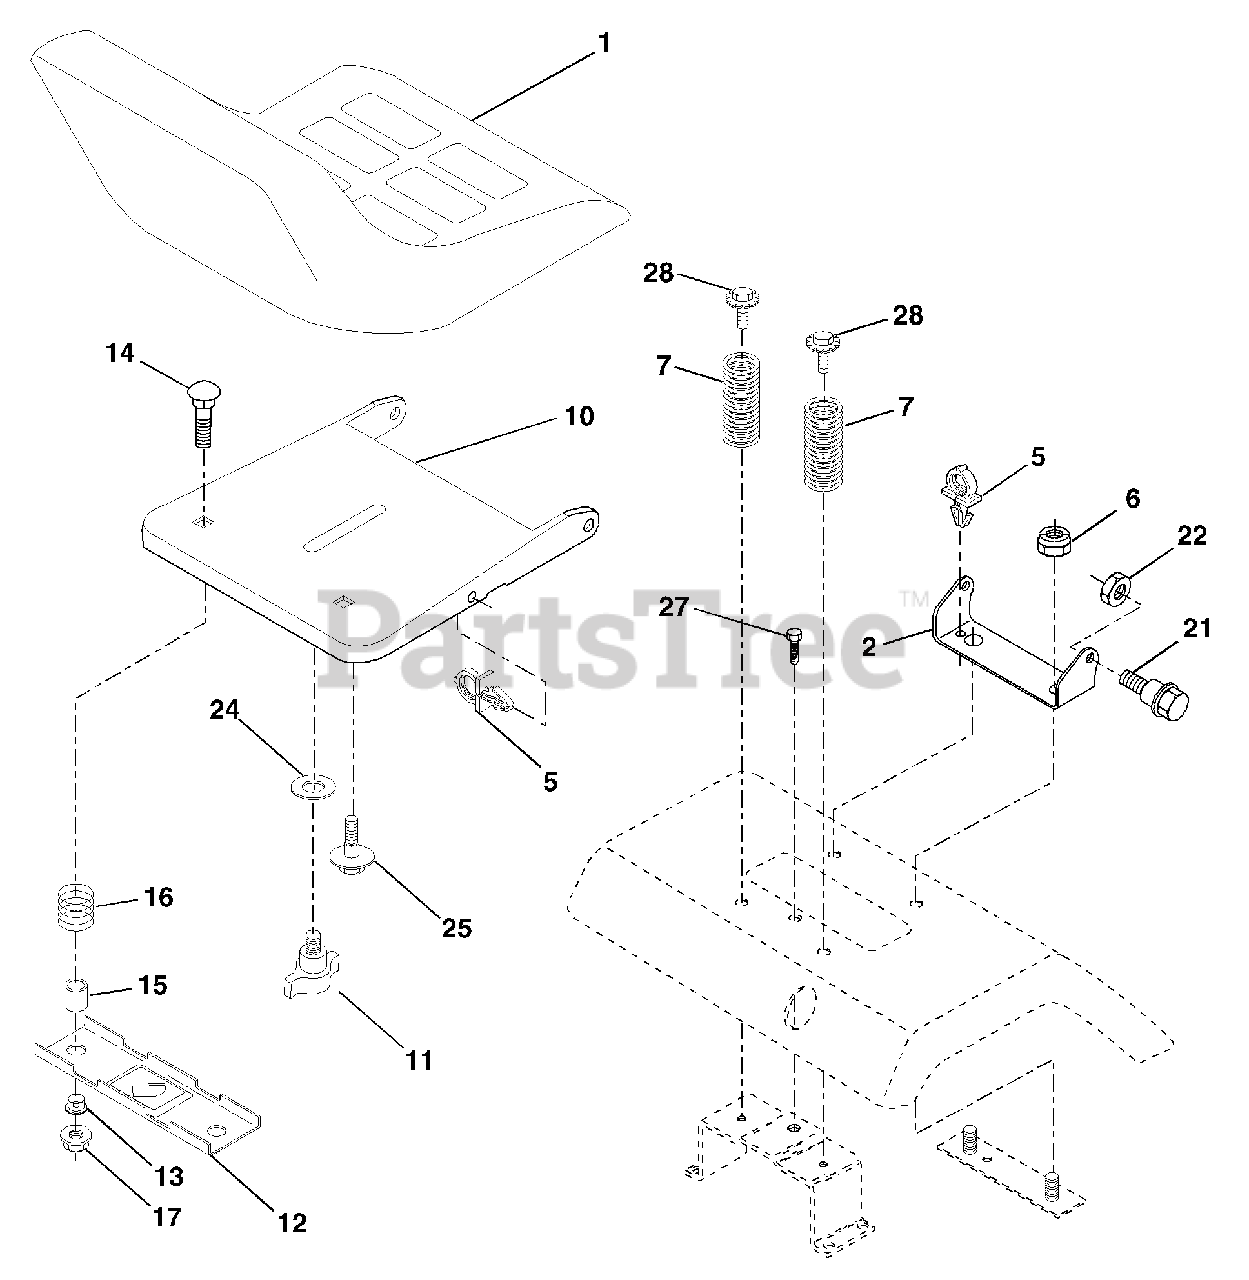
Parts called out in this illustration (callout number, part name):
1	Seat
2	Bracket Pivot Seat 8 720
5	Clip Push-In
6	Nut Hex w/Ins. 3/8-16 Unc
7	Spring Seat Cprsn 2 250 Blk Zi
10	Pan Seat
11	Knob Seat Adj. Wingnut
12	Bracket Mounting Switch
13	Bushing Snap Blk Nyl 50 Id
14	Bolt Rdhd Sqnk 1/4-20x1-1/2
15	Spacer Split 28 x 88
16	Spring Cprsn
17	Nut Lock 1/4 Lge Flg Gr 5 Zinc
21	Bolt Shoulder 5/16-18 Unc
22	Nut Hex Lock W/Ins 5/16-18
24	Washer 17/32 X 1-3/16 X 12 Ga.
25	Bolt Shoulder 5/16-18 X 62
27	Screw Thdrol 3/8-16 x 1/2
28	Bolt 5/16-18 Unc x 3/4 w/Sems
